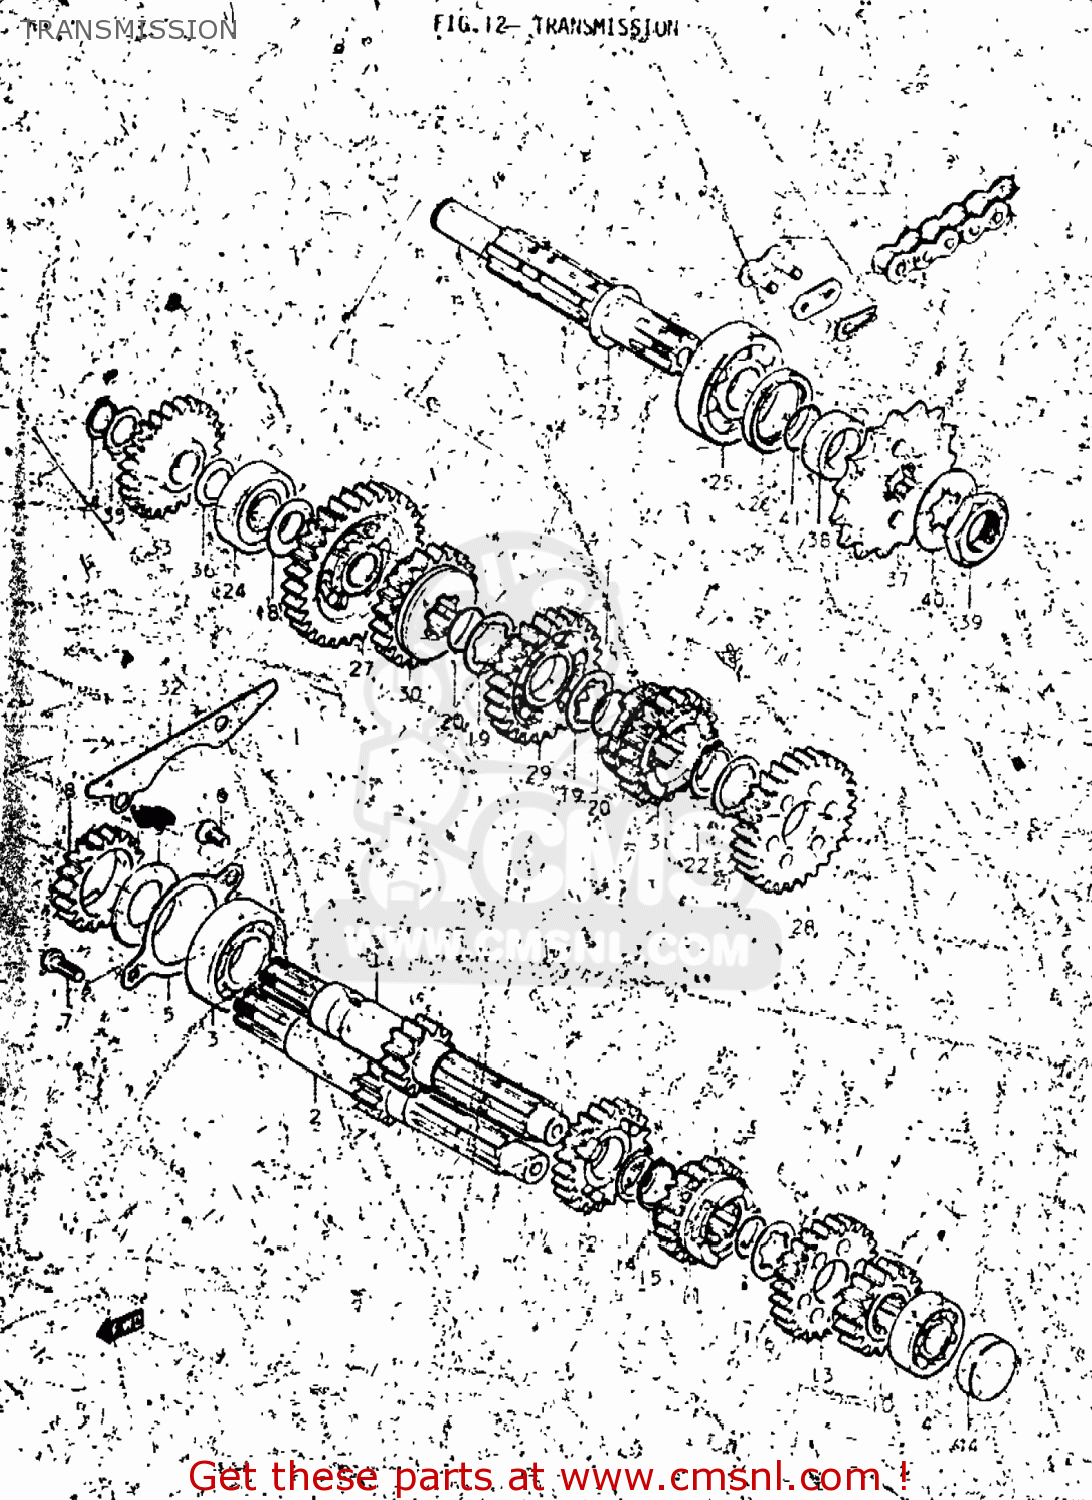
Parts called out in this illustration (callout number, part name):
1	SHAFT,COUNTER
2	SHAFT,COUNTER
3	BEARING
4	BEARING
5	PLATE,COUNTERSHAFT BEARING
6	SCREW
7	SCREW
8	GEAR,KICK STARTER DRIVE
9	WASHER(25X41X3)
10	GEAR,SECOND DRIVE
11	GEAR,THIRD DRIVE
12	GEAR,FOURTH DRIVE
13	GEAR,FIFTH DRIVE
14	SHIM
15	CIRCLIP
16	WASHER,LOCK
17	CIRCLIP
18	WASHER,THRUST
19	WASHER
20	RING,SNAP
21	WASHER
22	RING,SNAP
23	SHAFT,DRIVE
24	BEARING
25	BEARING
26	SEAL,OIL(32X42X6)
27	GEAR,FIRST DRIVEN
28	GEAR,SECOND DRIVEN
29	GEAR,THIRD DRIVEN
30	GEAR,FOURTH DRIVEN
31	GEAR,5TH DRIVEN
32	PLATE,OIL RESERVOIR
33	GEAR,KICK STARTER IDLE
34	CIRCLIP
35	WASHER
36	WASHER
37	SPROCKET,ENGINE
38	SPACER(22X32X11.5)
39	NUT
40	WASHER,LOCK
41	O RING(D:1.7,ID:22)
42	CHAIN ASSEMBLY,DRIVE
43	JOINT ASSEMBLY,CHAIN
44	PLUG
